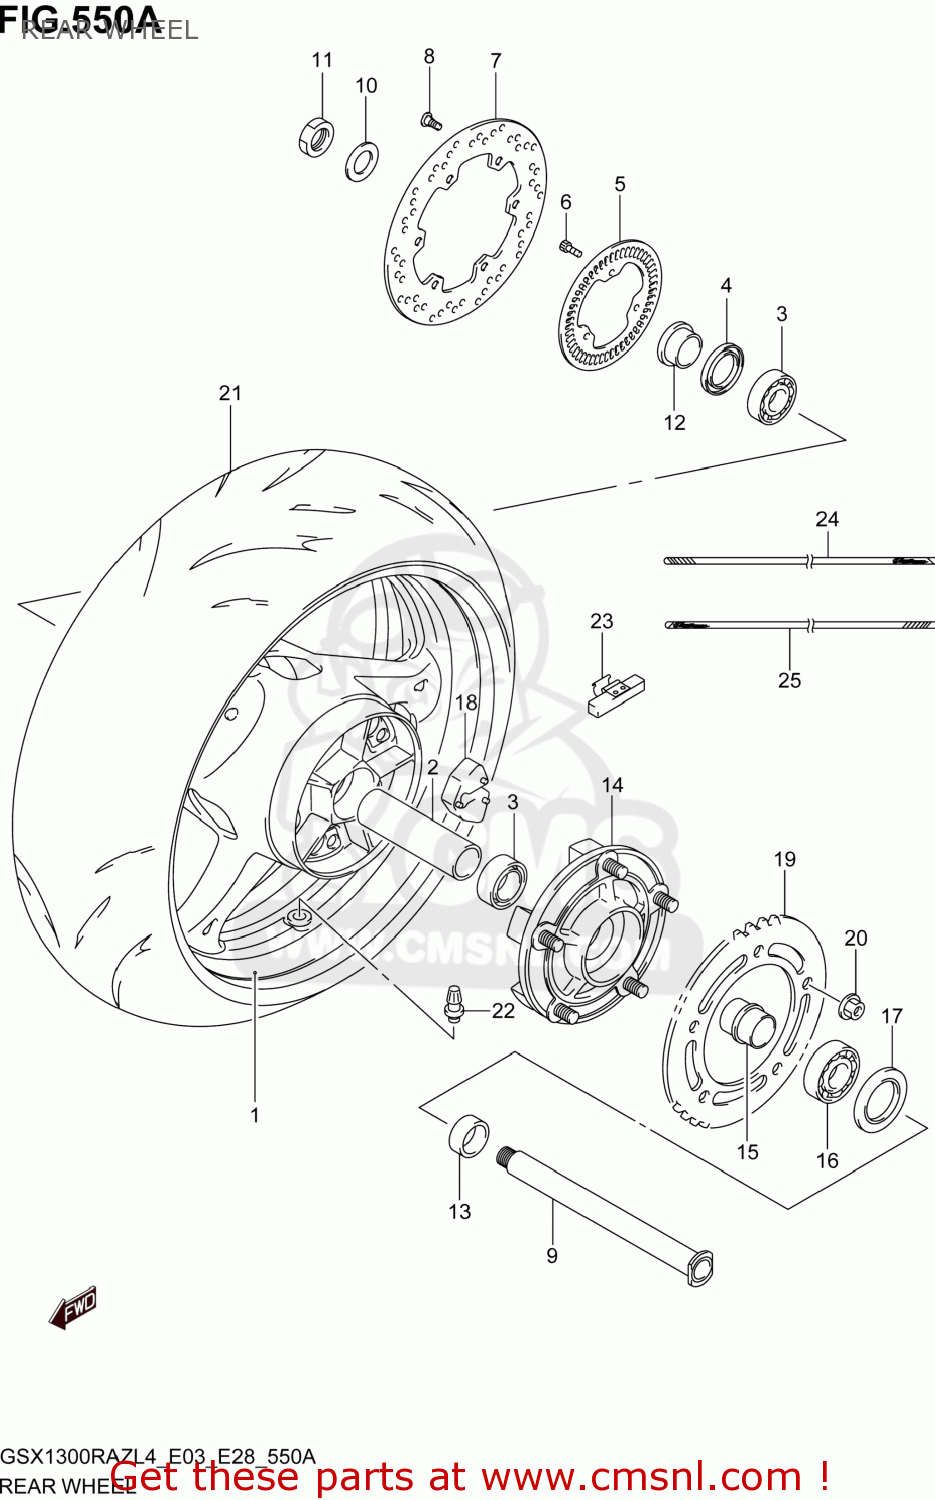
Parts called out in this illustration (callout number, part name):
1	WHEEL,RR(17M/CXMT6.00)
2	SPACER,RR WHEEL BEARING
3	BEARING(28X52X12)
4	SEAL,OIL(37X52X8)
5	RING,SPEED SENSOR RR(60T)
6	BOLT
7	DISC,RR BRAKE
8	BOLT(8X21)
9	AXLE,RR
10	WASHER(25.2X42X3.2)
11	NUT
12	SPACER,RR AXLE,R
13	SPACER,RR AXLE,L
14	DRUM,RR SPROCKET
15	RETAINER,RR SPROCKET DRUM
16	BEARING(32X65X17)
17	SEAL,OIL(39X65X7)
18	ABSORBER,RR HUB SHOCK
19	SPROCKET,RR(43T-530)
20	NUT
21	TIRE,RR
22	VALVE ASSY,WHEEL RIM(TR412)
23	BALANCER,WHEEL(10G)
24	TAPE,WHEEL FRONT,R
25	TAPE,WHEEL FRONT,L
